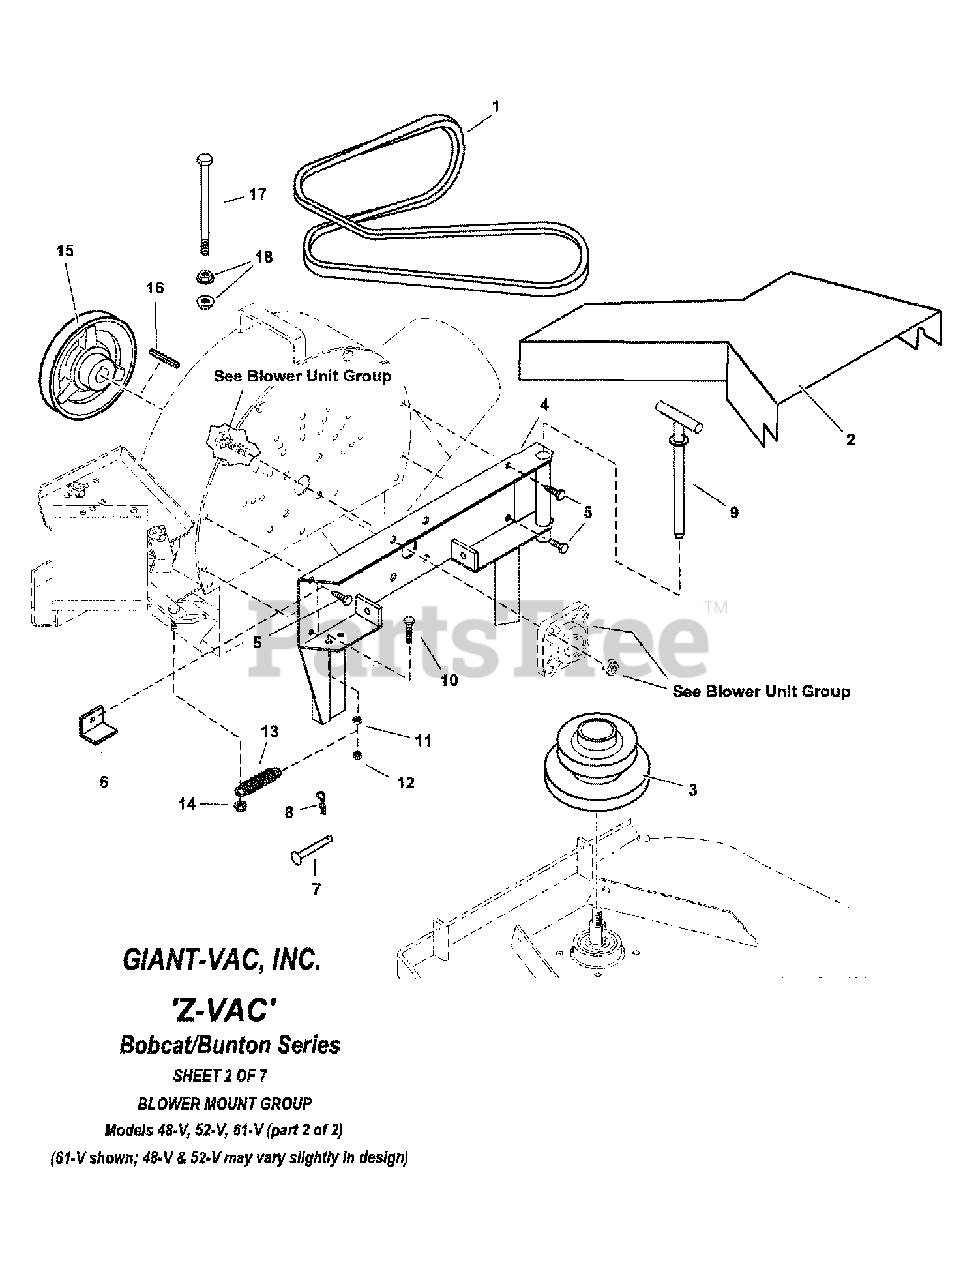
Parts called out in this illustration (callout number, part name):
1	BELT, Blower Unit Drive, Model 48-V, 61-V
1	BELT, Blower Unit Drive, Model 52-V
2	WELDMENT, 48" Belt Shield
2	WELDMENT, 52" Belt Shield
2	WELDMENT, 61" Belt Shield
3	PULLEY, Deck, Bobcat
4	WELDMENT, Mounting Bracket, 48" Fast-Vac
4	WELDMENT, Mounting Bracket, 52" Fast-Vac
4	WELDMENT, Mounting Bracket, 61" Fast-Vac
5	SCREW, 5/16-18 x 3/4" Hex Washer Self-Tap
6	CLIP, Belt Guard Support
7	ROD, Quick Connect
8	HAIRPIN, Cotter
9	WELDMENT, T-Handle Pin
10	SCREW, 5/16-18 x 1" Hex Head Cap, GR5
11	NUT, 5/16-18 Hex Flange Lock
12	NUT, 5/16-18 Hex Center Lock, GR B
13	SPRING, Idler, Fast Vac
14	NUT, 5/16-18 Hex Center Lock, GR B
15	PULLEY, Blower Input, Model 48-V & 52-V
15	PULLEY, Blower Input, Model 61-V
16	KEY, 1/4 Square x 1-7/16"
17	SCREW, 3/8-16 x 6" Hex Head Cap, GR5
18	NUT, 5/16-18 Hex Large Flange Center Lock
